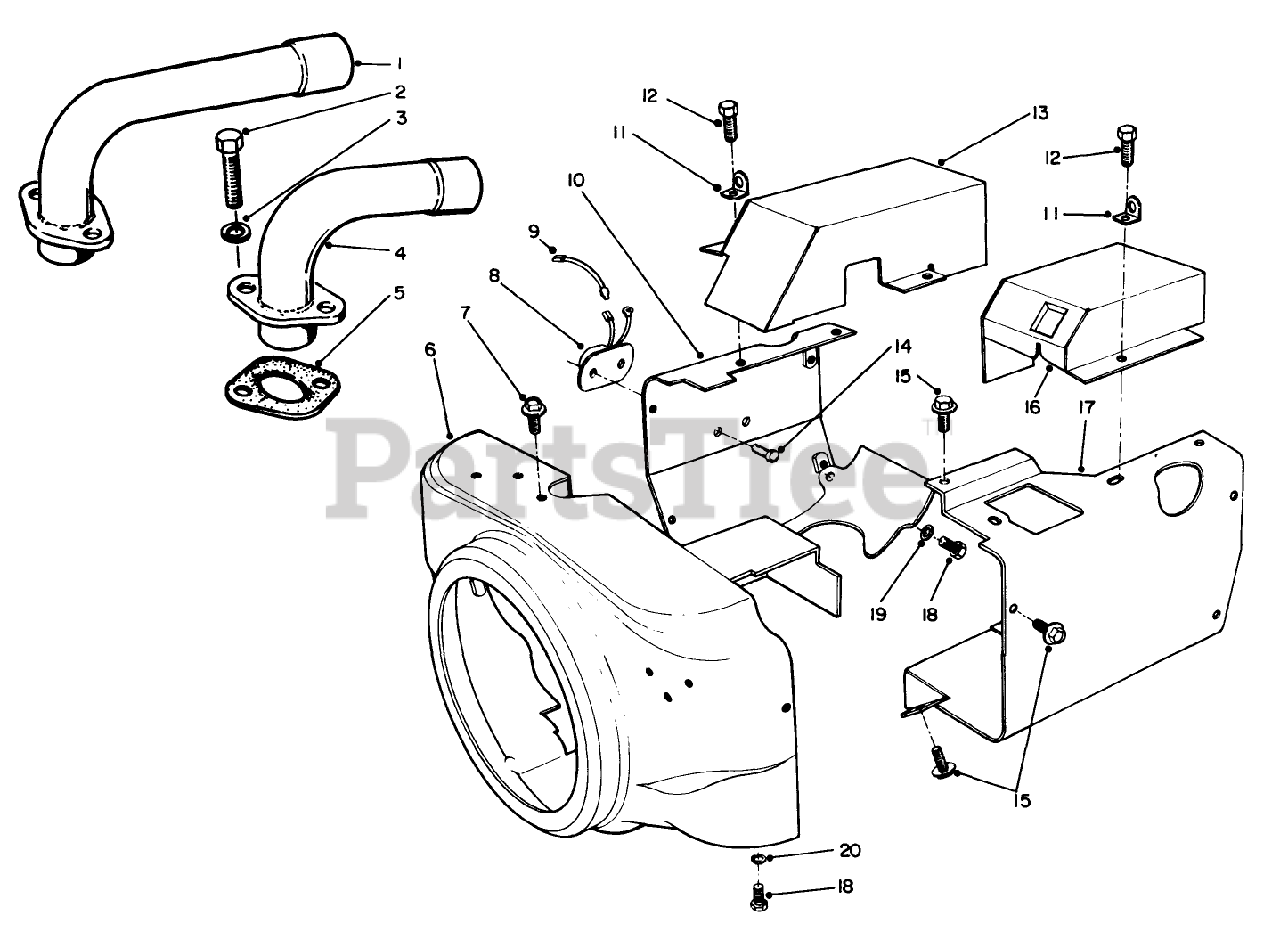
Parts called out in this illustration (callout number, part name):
1	EXHAUST TUBE
2	SCREW-HH
3	WASHER-LOCK
4	EXHAUST TUBE
5	GASKET
6	Housing, Blower
7	HEX HD CAPSCREW
8	SWITCH ASM
10	CYLINDER HSG
11	Bracket-Lift
12	SCREW-HWH
13	Cover, Exhaust-Left
14	Rivet, High Air Temp. Cut Off
15	SCREW-HWH
16	Cover, Exhaust-Right
17	RH CYL/ARM HSG
18	SCREW-HH
19	WASHER-FLAT
20	WASHER-FLAT
